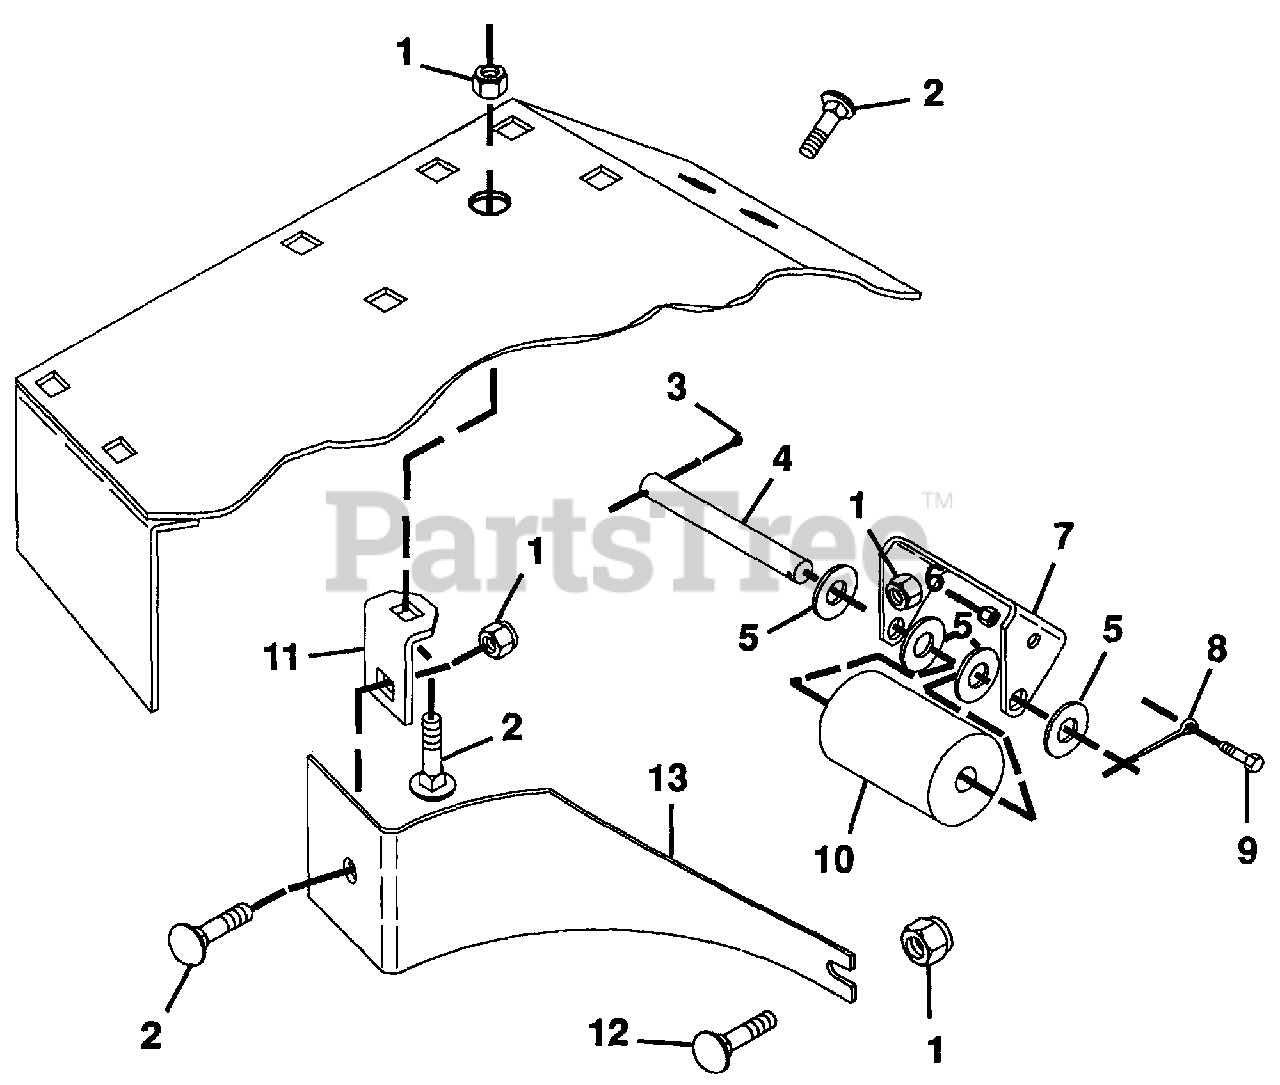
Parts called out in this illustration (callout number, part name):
1	NUT, LOCK 3/8-16
2	BOLT, 3/8-16X1.00 RD HD SQ NK
3	PIN, COTTER .25X1.00
4	ROD
5	WASHER, FLAT .656X1.312X.095
6	NUT, HEX 1/4-20
7	BRACKET, ROLLER
8	PIN, COTTER .25X2.00
9	BOLT, HEX 1/4-20X.75
10	ROLLER, GAGE
11	BRACKET
12	BOLT, CARRIAGE 3/8-16X.75
13	SCROLL
